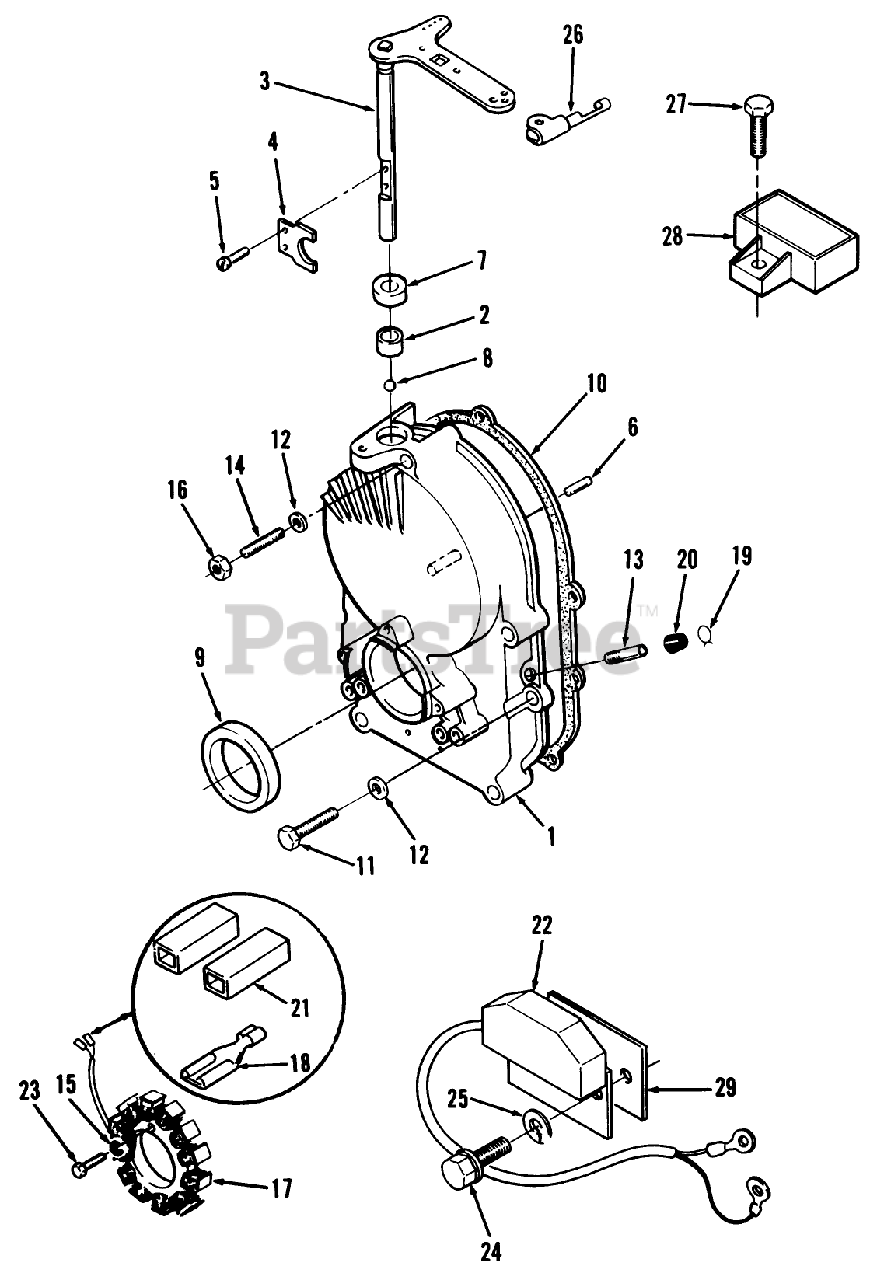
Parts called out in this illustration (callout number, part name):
3	SHAFT AND ARM
5	*Screw, Machine-Pan Head (8-32 x 3/8")
6	PIN-DOWEL
12	WASHER
16	NUT-GEAR COVER
20	CAP-FUEL OUTLET
21	BODY-TERM. CONNECTOR KIT
25	WASHER-LOCK
27	SCREW-HWH
